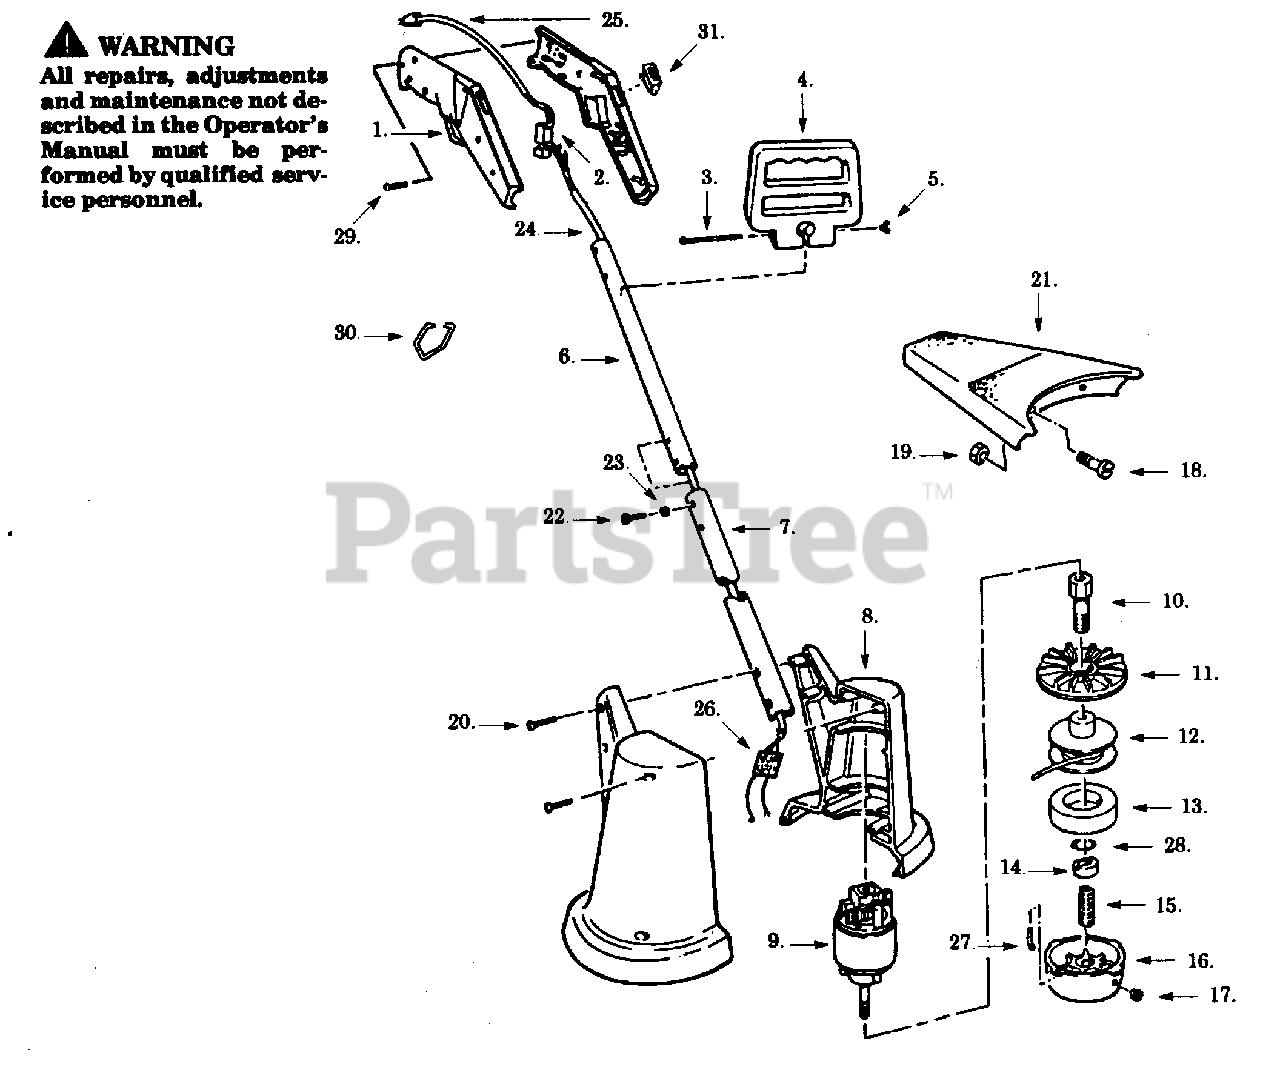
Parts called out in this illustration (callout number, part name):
1	R.H./L.H. Handle
2	Trigger Switch
4	Side Handle
5	Wing Nut
6	Upper Handle Tube
7	Lower Handle Tube
8	L.H./R.H. Housing
10	Drive Adapter
11	Rear Plate
12	Spool & Line
13	Foam Pad
14	Drive Adapter Nut
15	Compression Spring
21	Tail Guard
23	Lockwasher
25	Power Cord
26	Rectifier Kit
27	Cotter Pin
31	Switch Power
